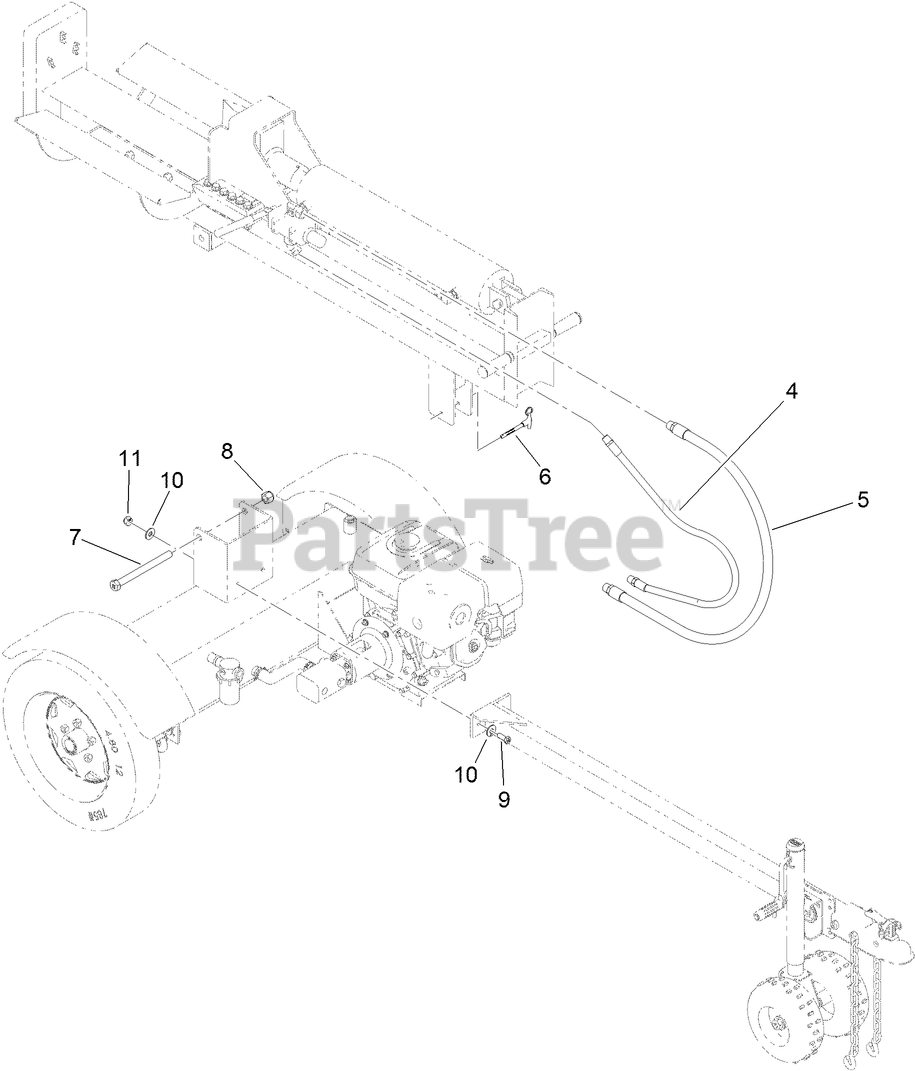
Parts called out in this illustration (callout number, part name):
4	HYD HOSE ASM
5	HYD HOSE ASM
6	PIN
7	BOLT-HH
8	NUT-LOCK, NI
9	SCREW-HH
10	WASHER-FLAT
11	NUT-LOCK
